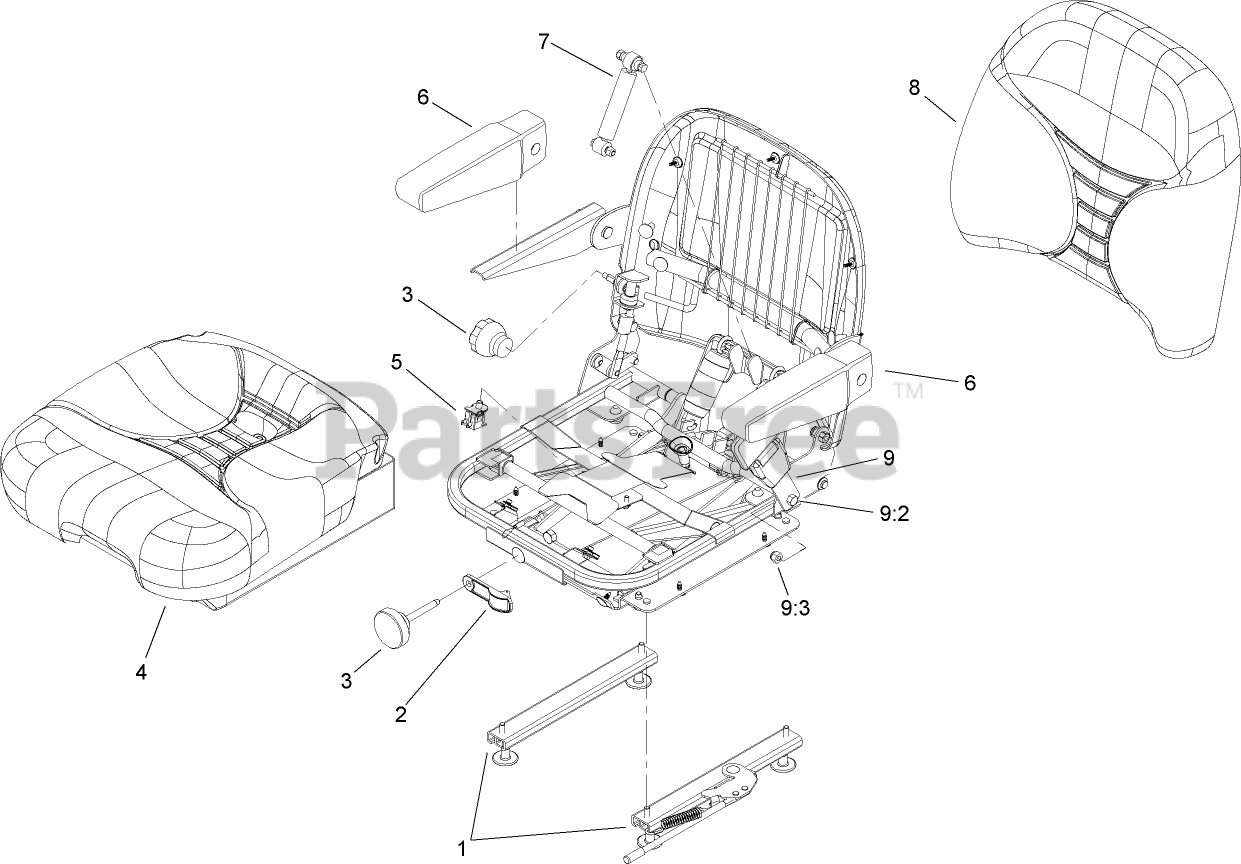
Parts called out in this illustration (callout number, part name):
1	Seat Track Kit
2	Weight Indicator Kit
3	Knob Kit
4	Bottom Cushion Kit
5	Switch Kit
6	PAD-ARMREST
7	Shock Absorber Kit
8	Back Cushion Kit
9	SEATBELT KIT
9:2	SCREW-HH
9:3	NUT-LOCK, NI
